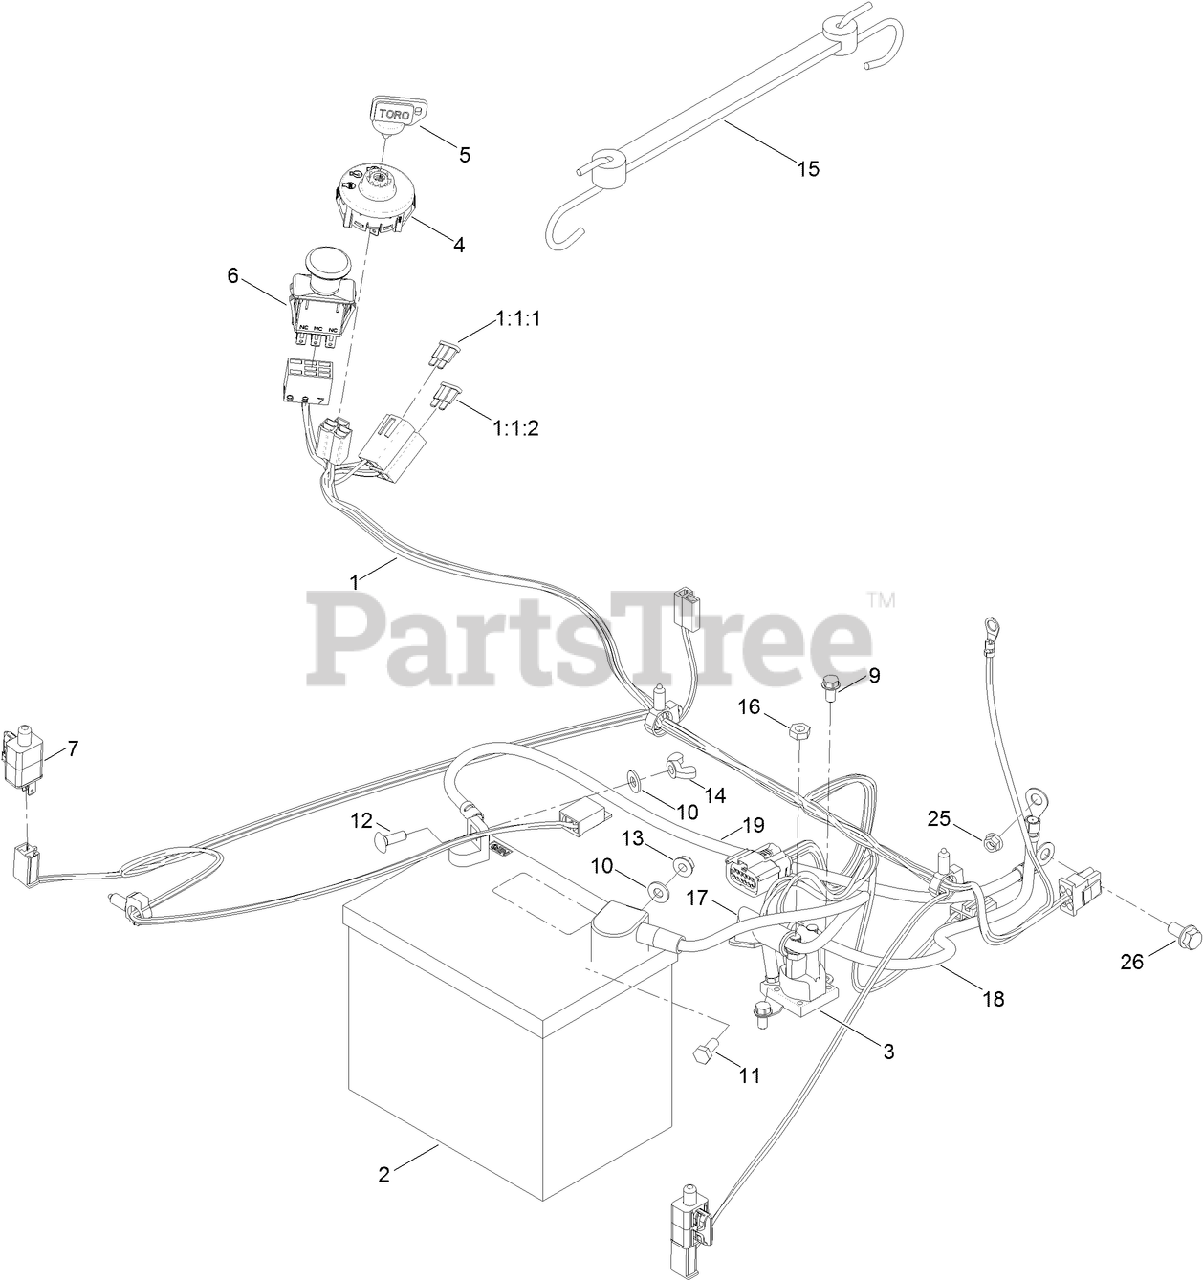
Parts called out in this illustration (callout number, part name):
1	HARNESS-WIRE
1:1:1	FUSE-BLADE, 30 AMP
1:1:2	FUSE-BLADE, 25 AMP
2	BATTERY
3	SOLENOID
5	KEY-IGNITION
6	SWITCH-PTO
7	SWITCH
9	SCREW-HWH
10	WASHER-FLAT
11	SCREW-HH
12	BOLT-CARR
13	NUT-HF
14	NUT-WING
15	HOLDDOWN-BATTERY
16	NUT-JAM
17	CABLE-BATTERY, RED
18	CABLE-BATTERY, POSITIVE
19	CABLE-BATTERY, BLACK
25	NUT-HF
26	SCREW-HHF
